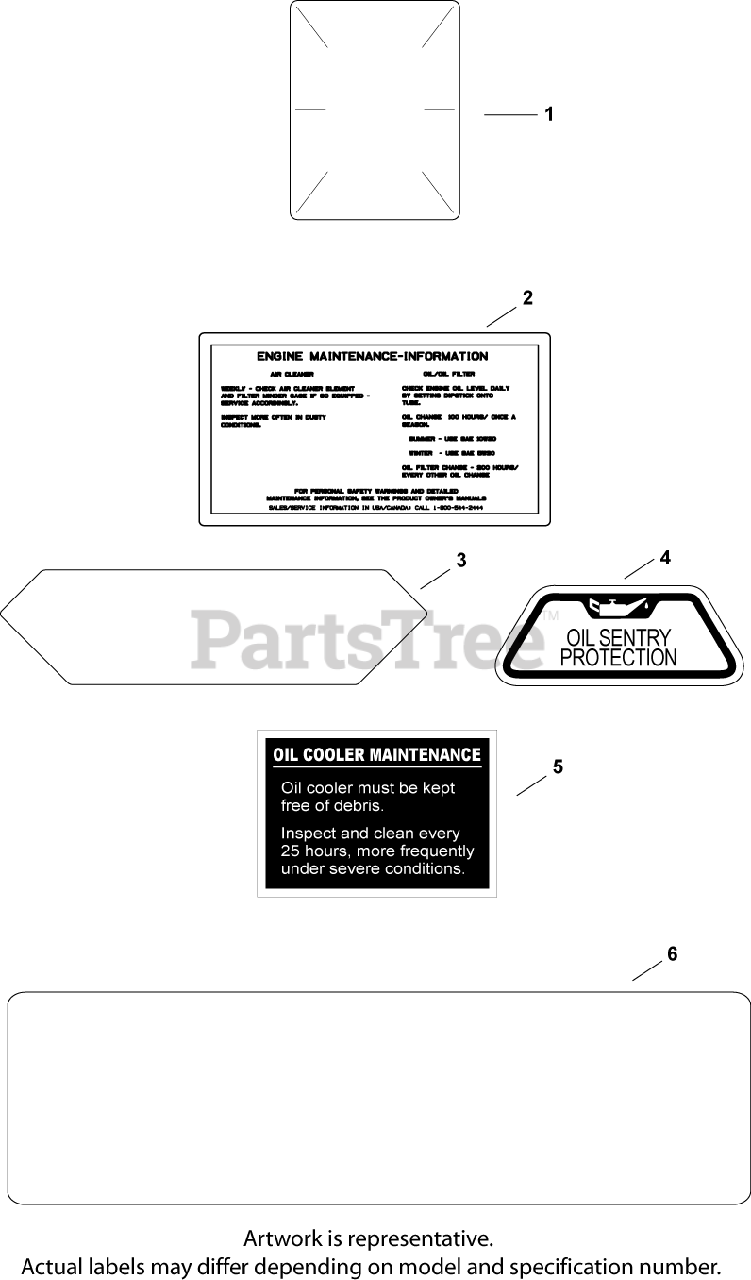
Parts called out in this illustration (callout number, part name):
1	DECAL, CLEAR LAMINATE USE 25 113 70-S
2	DECAL, AIR CLEANER - (#DSC)
3	DECAL, AIR FILTER COVER
4	DECAL, OIL SENTRY - (#DSC)
5	DECAL, OIL COOLER - (#DSC)
6	DECAL, 27 HP
